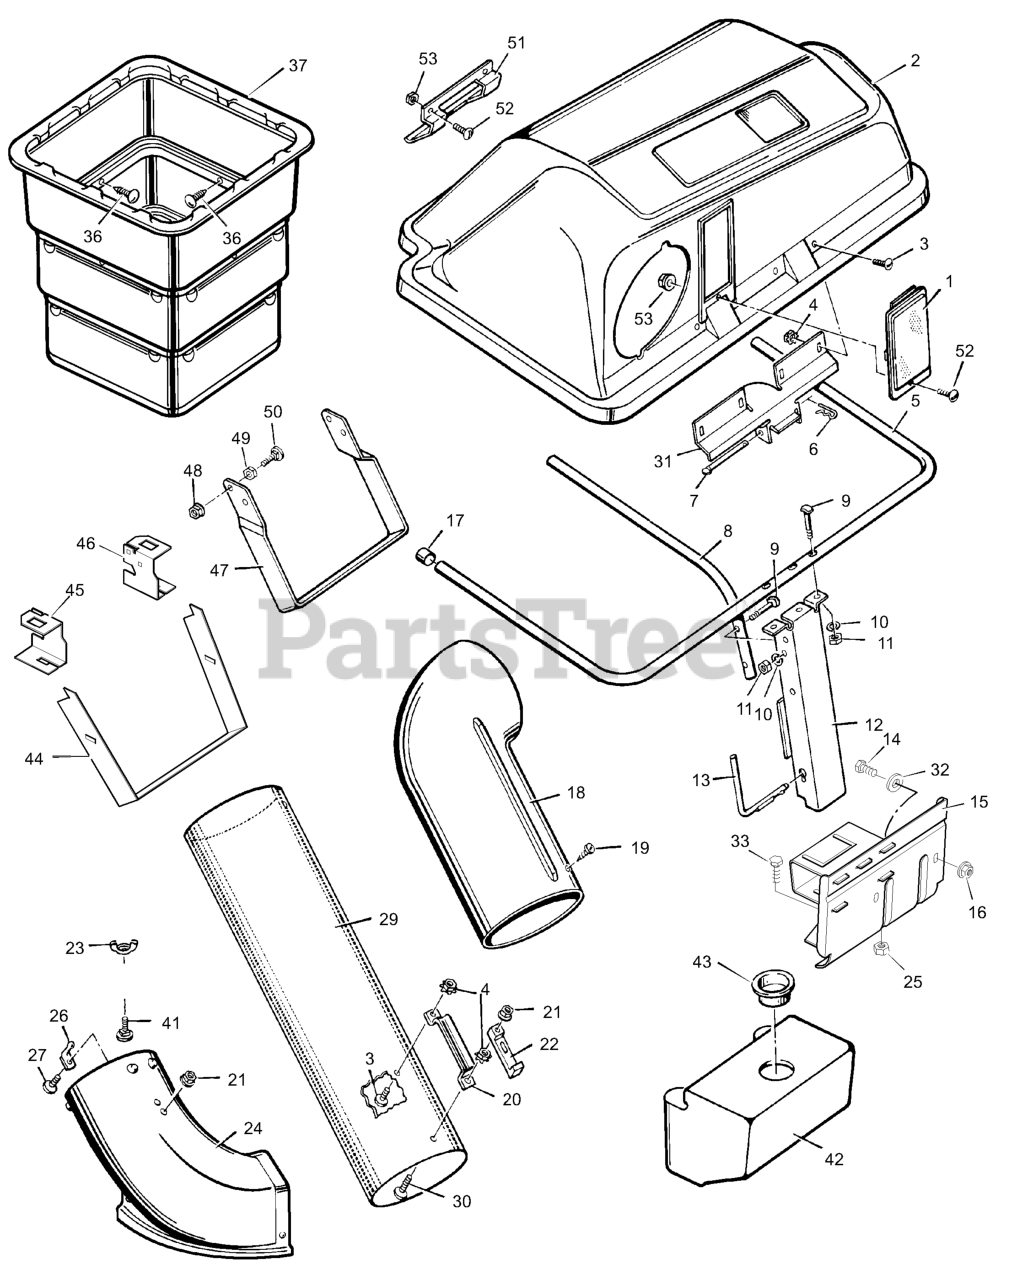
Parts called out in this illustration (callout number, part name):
4	Locknut
6	Pin, Hair
7	Pin, Hinge
8	Tube, Center
9	Bolt, Special
10	Lockwasher
11	Nut, Hex
12	Channel Assembly
13	Pin, Channel
14	CAPSCREW, Hex Head, 5/16-18 x 1
15	Mount Assembly, Bagger
16	Nut, Hex
17	Cap, End
20	HANDLE, Connect Tube
21	Locknut, Flange
22	Latch, Rubber
23	Wingnut
24	Tube, Extension
25	Hex Nut
26	Pin, Latch
27	Bolt, Carriage
29	Tube, Connector
31	Hinge, Cover
33	Bolt, Hex
36	Fastener, Plastic
37	Containers (Quantity 2)
41	Bolt, Carriage
42	Shell, Front Weight
43	Plug, Front Weight
44	Support, Weight (Type A)
45	Bracket, Right Hanger
46	Bracket, Left Hanger
47	Support, Weight (Type B)
48	Nut, Flange
49	Nut, Jam
50	Carriage, Bolt
51	Handle, Plastic
53	Nut, Hex
